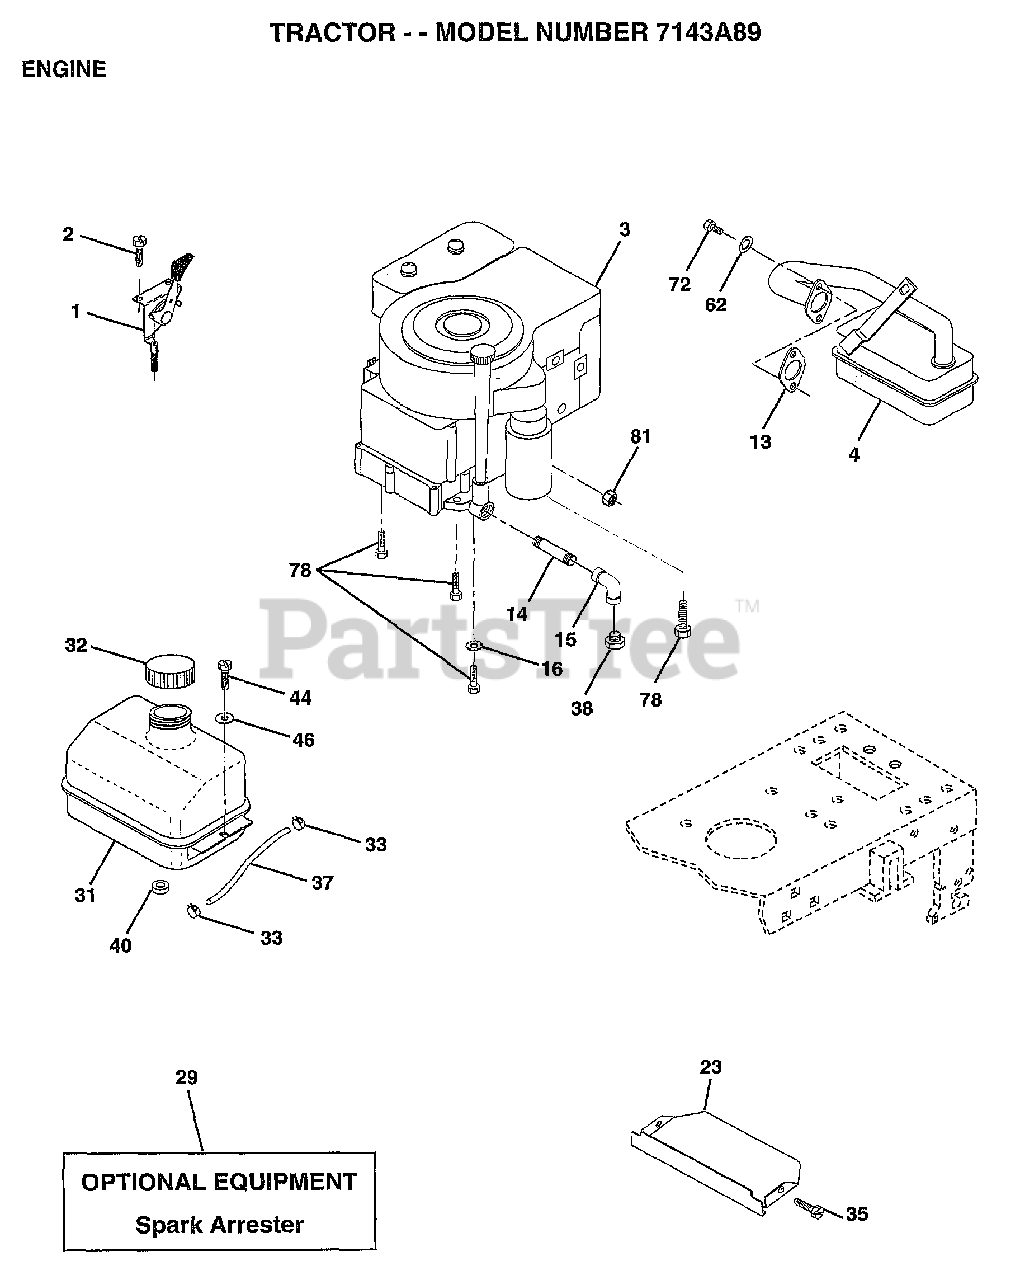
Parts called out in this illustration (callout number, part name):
1	CONTROL THROTTLE
2	SCREW LT
4	MUFFLER
13	GASKET ENG 1 313 LD TIN PLATED
14	PIPE NIPPLE
15	ELBOW
16	LOCKWASHER
23	SHIELD.BRN/DBR.GD
31	TANK.FUEL.LT.
32	CAP ASM FUEL
33	HOSE CLAMP
35	SCREW
37	LINE FUEL
44	SCREW HEX CRT
46	WASHER
62	LOCKWASHER
72	SCREW
78	SCREW
81	NUT
